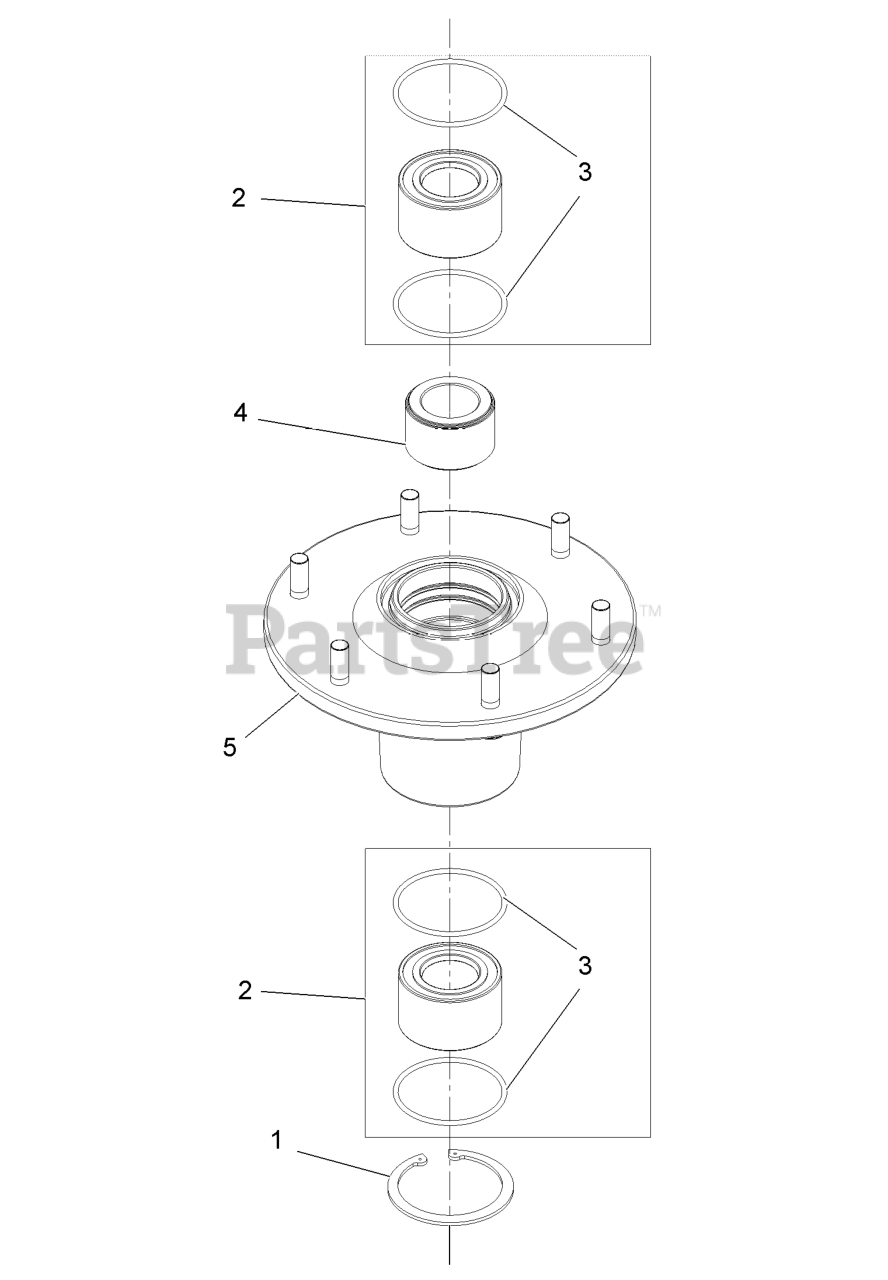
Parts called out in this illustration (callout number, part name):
1	RING-RETAINING
2	ASM, BEARING W/ORINGS
4	SPACER,BEARING
5	ASM,HOUSING W/STUDS
